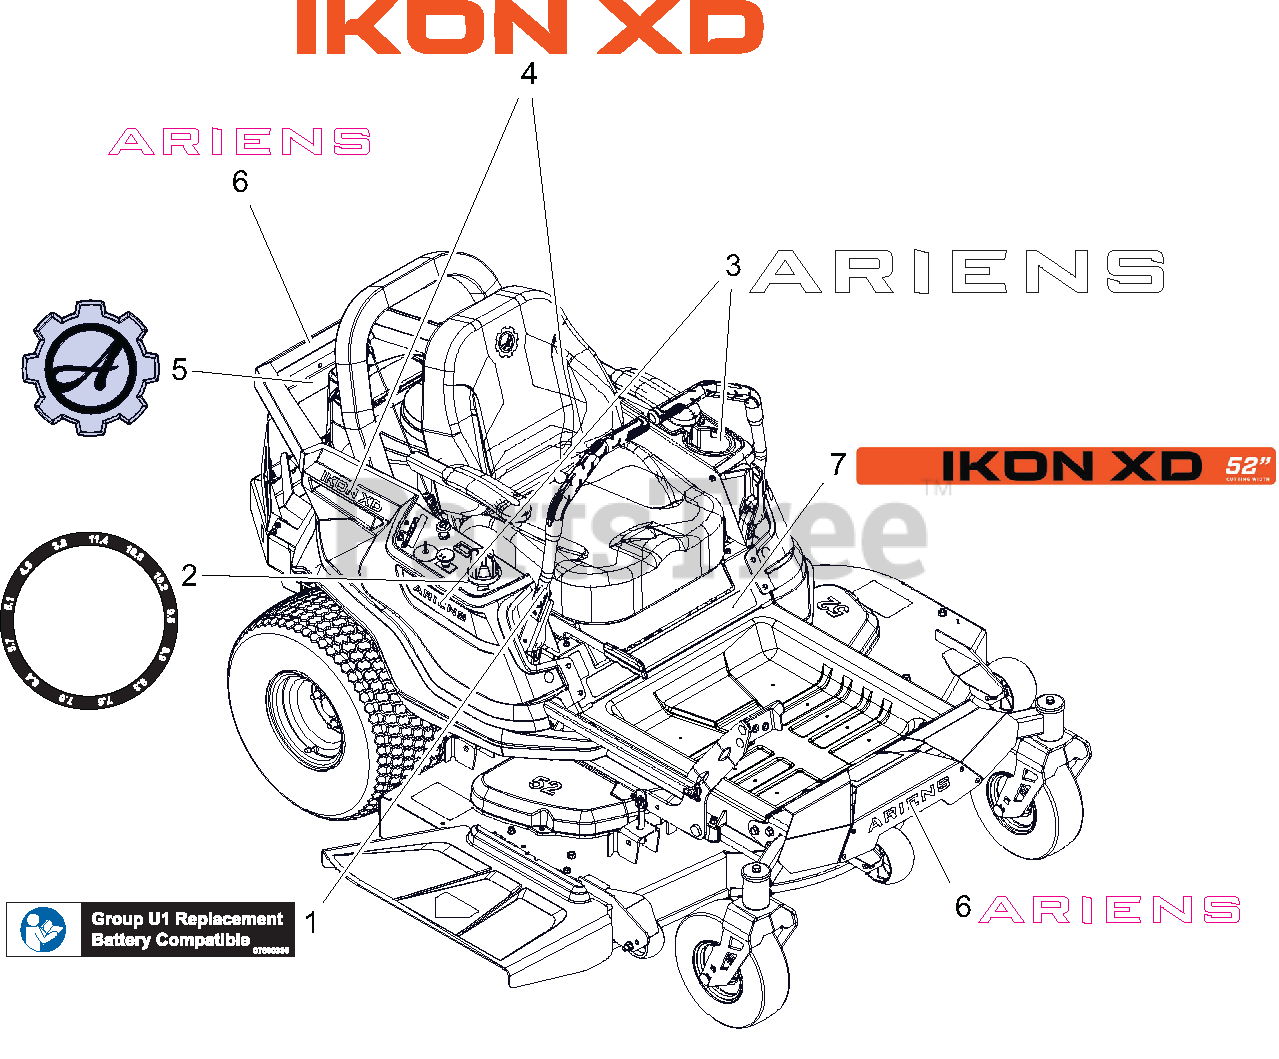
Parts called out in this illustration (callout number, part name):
1	DECAL, U1 BATTERY REPLACEMENT
2	DECAL, CUT HEIGHT - IKON CE
3	DECAL, ARIENS (6.50")
4	DECAL, FENDER - IKON XD
5	DECAL- ARIENS GEAR BADGE
6	DECAL - ARIENS 9.625"
7	DECAL - IKON XD - 52
